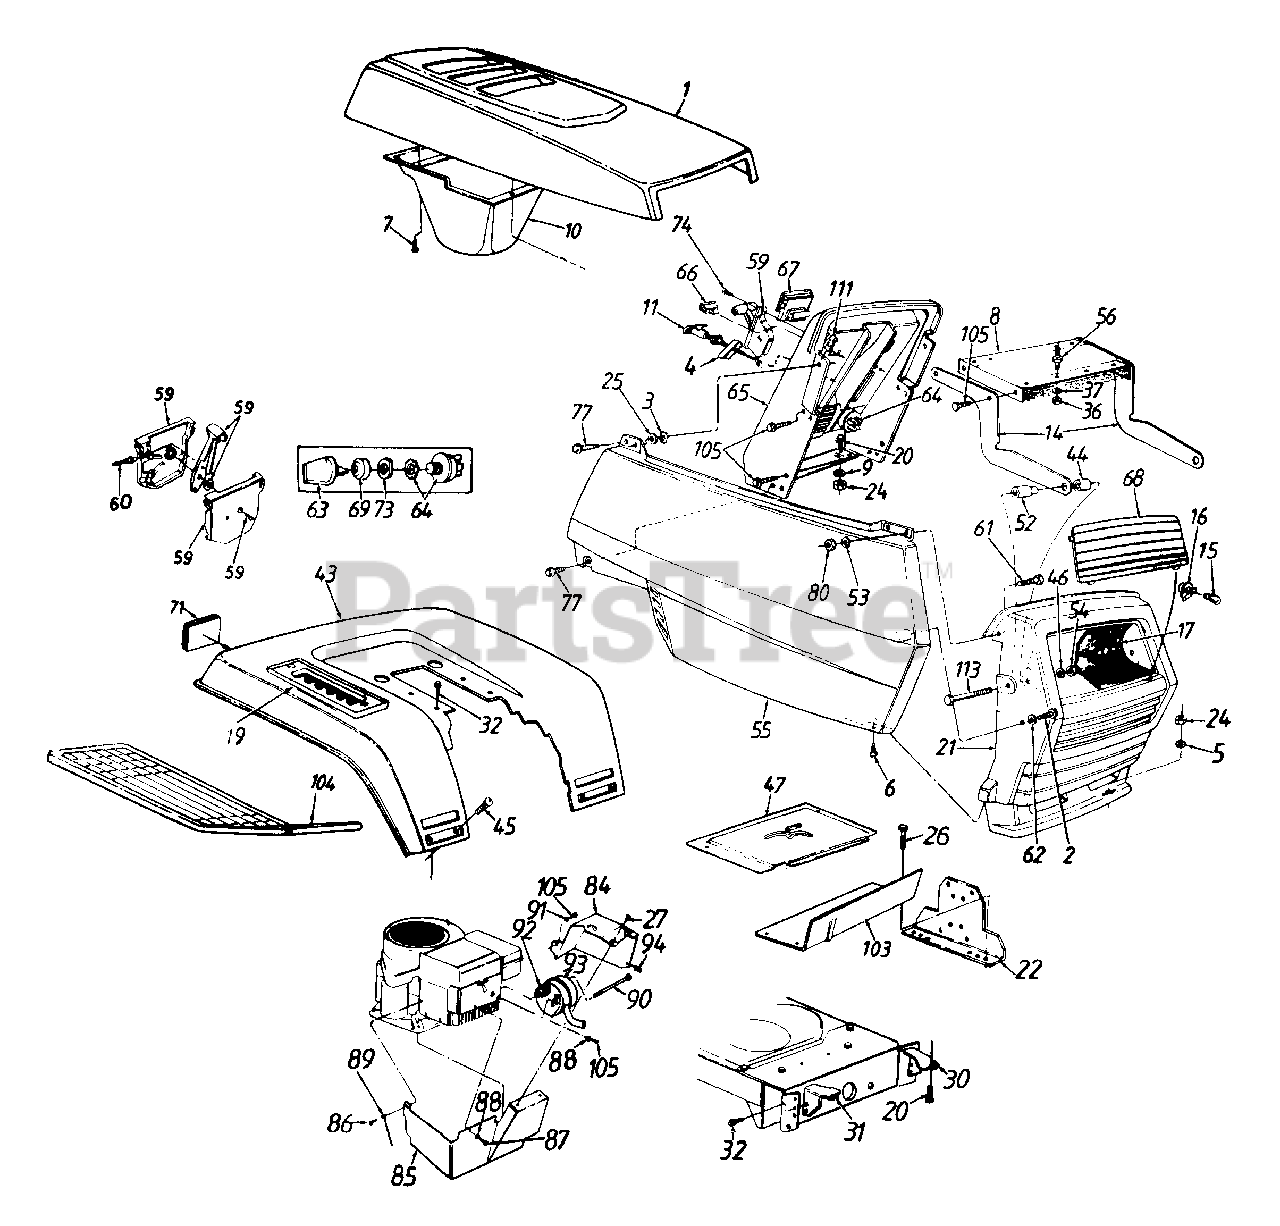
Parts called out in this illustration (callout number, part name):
1	Hood
2	Hex Wash. B-Tap Scr. 1/4 x .62" Lg.
3	Bolt Retainer 1/4" I.D.
4	Retainer Clip
5	Fl-Wash. .34" I.D. x 1"
6	Truss Mach. B-Tap Scr. #10 x .5" Lg.
7	Hex Wash. Hd. AB-Tap Scr. #8 x .5" Lg.
11	Choke Control 29" Lg.
14	Hood Hinge
15	Lamp
16	Twist Lock - Lamp Socket
17	Reflector - Headlight
21	Grille
24	Hex Nut 5/16-18 Thd.
25	Fl-Wash. 1/4" I.D. x .93" O.D.
26	Hex Wash. Hd. B-Tap Scr. 5/16-18 x .5" Lg.
27	Hex B-Tap Scr. #10 x .38" Lg.
30	Grille Mount Brk't. - L.H.
31	Grille Mount Brkt. - R.H.
32	Hex Wash. Hd. AB-Tap Ser, 5/16 x .75" Lg.
36	Hex Nut 1/4-20 Thd.
37	Bell-Wash. .265" I.D. x .75"
45	Carriage Bolt 1/4-20 x .50" Lg.
46	Fl-Wash. .328" I.D. x .68" O.D.
52	Shld. Spacer .33" I.D.
53	Fl-Wash. .281" I.D. x .5" O.D.
54	Hex Cent. L-Nut 5/16-18 Thd.
55	Side Cover - R.H.
56	Double Ended Stud 1/4-20 Thd.
59	Throttle Control Box Ass'y.
60	Throttle Control Wire 18.5" Lg.
61	Hex Bolt 1/4-20 x .62" Lg.
62	Fl-Wash. .281" I.D. x .73" O.D.
64	Ignition Switch
66	Light Switch
67	Ammeter
68	Lens
69	Ignition Switch Cap
71	Reflector
73	Ignition Switch Nut
74	Truss Mach. AB-Tap Scr. #10 x .5" Lg.
77	Hex Wash. Hd. Tap Scr. 1/4 x .75" Lg.
80	Hex L-Nut 1/4-20 Thd.
84	Muffler Heat Shield - L.H.
85	Muffler Heat Shield - R.H.
86	Pan Hd. Mach. Scr. 5/16-18 x .75" Lg.
87	Hex Bolt 1/4-20 x 3/8" Lg.
88	Spr. Wash. .265" I.D.
90	Shld. Bolt 7/16" Dia. x 3-5/8" Lg.
91	L-Wash. 1/4" I.D.
92	Gasket
93	Muffler
94	Speed Nut #10-24 Thd.
105	Hex Tap Scr. 1/4-20 x .5" Lg.
111	Speed Nut 1/4-20 Thd.
113	Hex Bolt 5/16-18 x 2.75"
